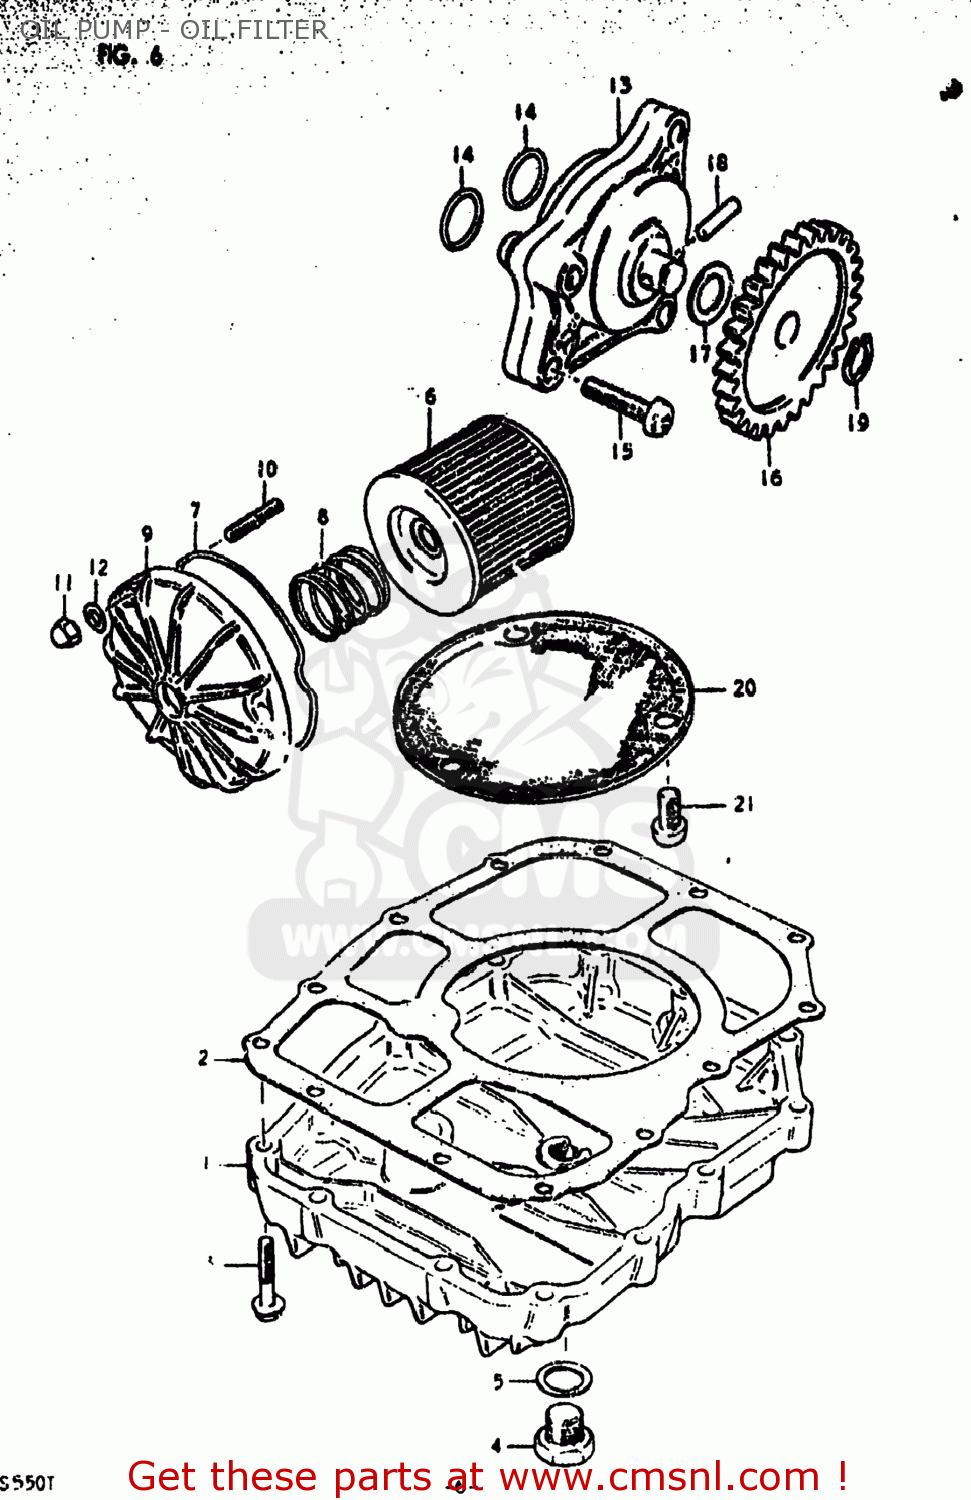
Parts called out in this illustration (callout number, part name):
1	PAN,OIL
2	GASKET,OIL PAN (MCA)
3	BOLT
4	PLUG
5	GASKET(14X19.2X2) (NAS)
6	FILTER ASSY,ENGINE OIL
7	O RING,OIL FILTER CHAMBER CAP
8	SPRING
9	CAP,OIL FILTER
10	STUD 6X20
11	NUT
12	WASHER
13	PUMP ASSEMBLY,OIL
14	O RING(D:1.9,ID:13)
15	SCREW
16	GEAR,OIL PUMP DRIVEN
17	SHIM
18	PIN(4X15.8)
19	CIRCLIP
20	STRAINER,ENGINE OIL
21	SCREW 6X12
